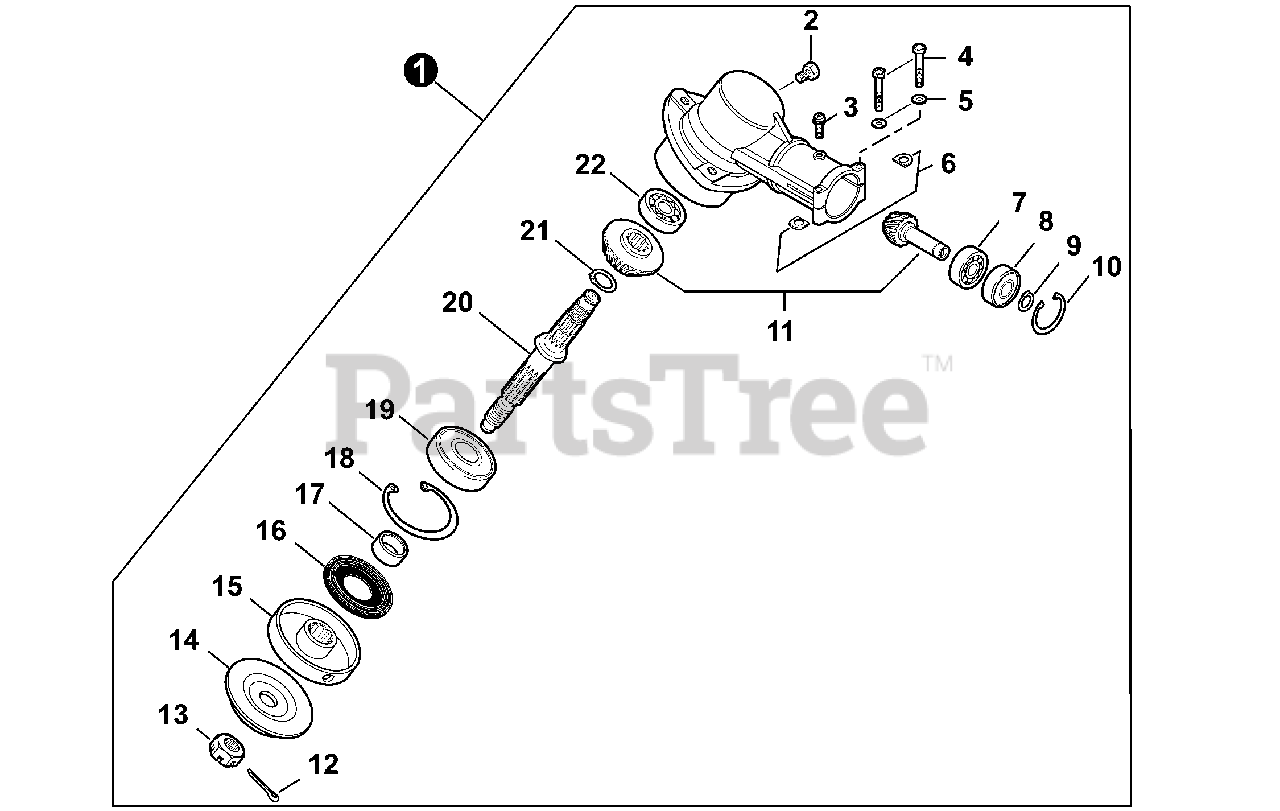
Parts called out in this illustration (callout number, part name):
1	GEAR CASE ASSY
2	BOLT M8×8
3	SCREW 5×10
4	BOLT 5×35 SP
5	WASHER, FLAT 5.5×10×0.8
7	BEARING, BALL 6900
8	BEARING, BALL 6900Z
9	RING, SNAP Ø10
10	RING, SNAP Ø22
11	GEAR SET
12	PIN, COTTER 2×22
14	PLATE, ADAPTOR - LOWER
15	PLATE, ADAPTOR - UPPER
16	SEAL, OIL 22
17	SPACER 11.8×15×9
18	RING, SNAP Ø32
19	BEARING, BALL 6201
20	SHAFT, GEAR
21	RING, SNAP Ø12
22	BEARING, BALL 609
